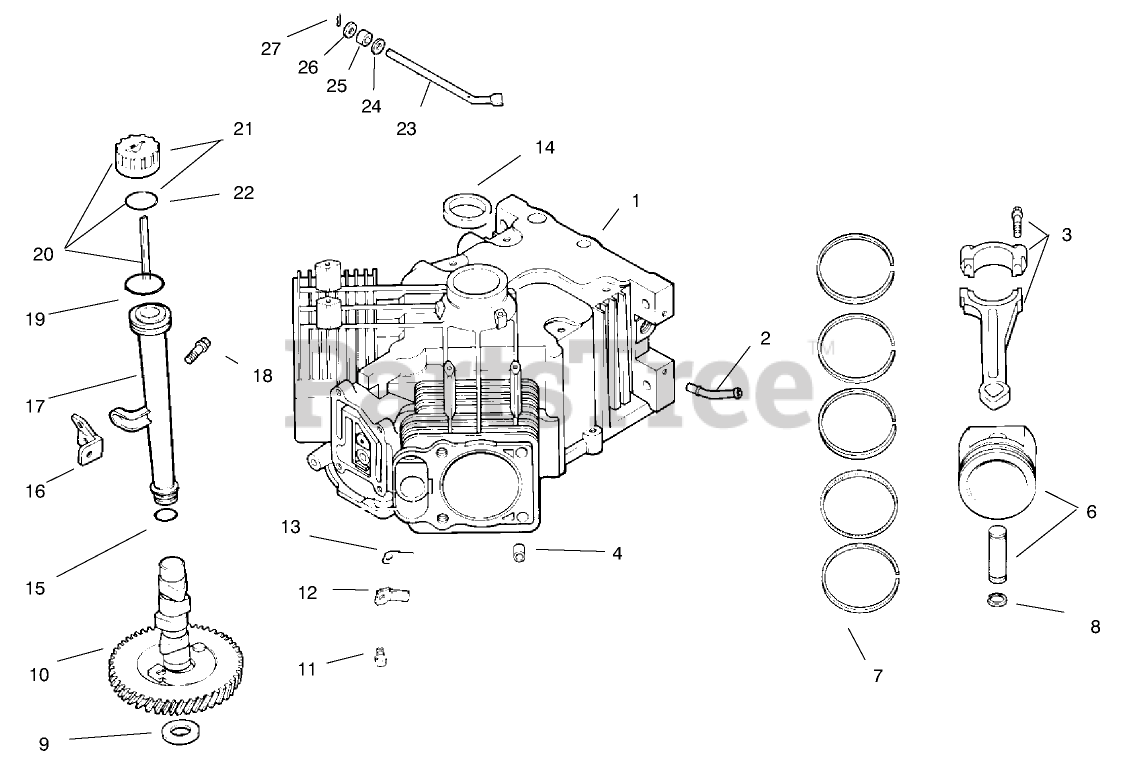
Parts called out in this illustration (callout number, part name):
1	Miniblock
1	Short Block
2	Fitting
3	Connecting Rod (std)
4	Pin-Dowel
5	Plug
6	Piston ASM STD INC4/7/8
7	Ring Set(Std.)
8	Retainer-Piston Pin
9	Shim-Camshaft
10	Camshaft
11	Screw
12	Retainer-Reed
13	Beed-Breather
14	Seal-Oil
15	"O"Ring
16	Bracket-Oil Tube
17	Tube-Oil Fill
18	Screw-HF
19	"O"Ring
20	Dipstick Asm (Incl. Ref.# 21-22)
21	Kit-Oil Fill Cap (Incl. Ref.# 22)
22	"O"Ring
23	Shaft-Governor Cross
24	Washer
25	Seal-Cross Shaft
26	Washer
27	Pin-Hitch
